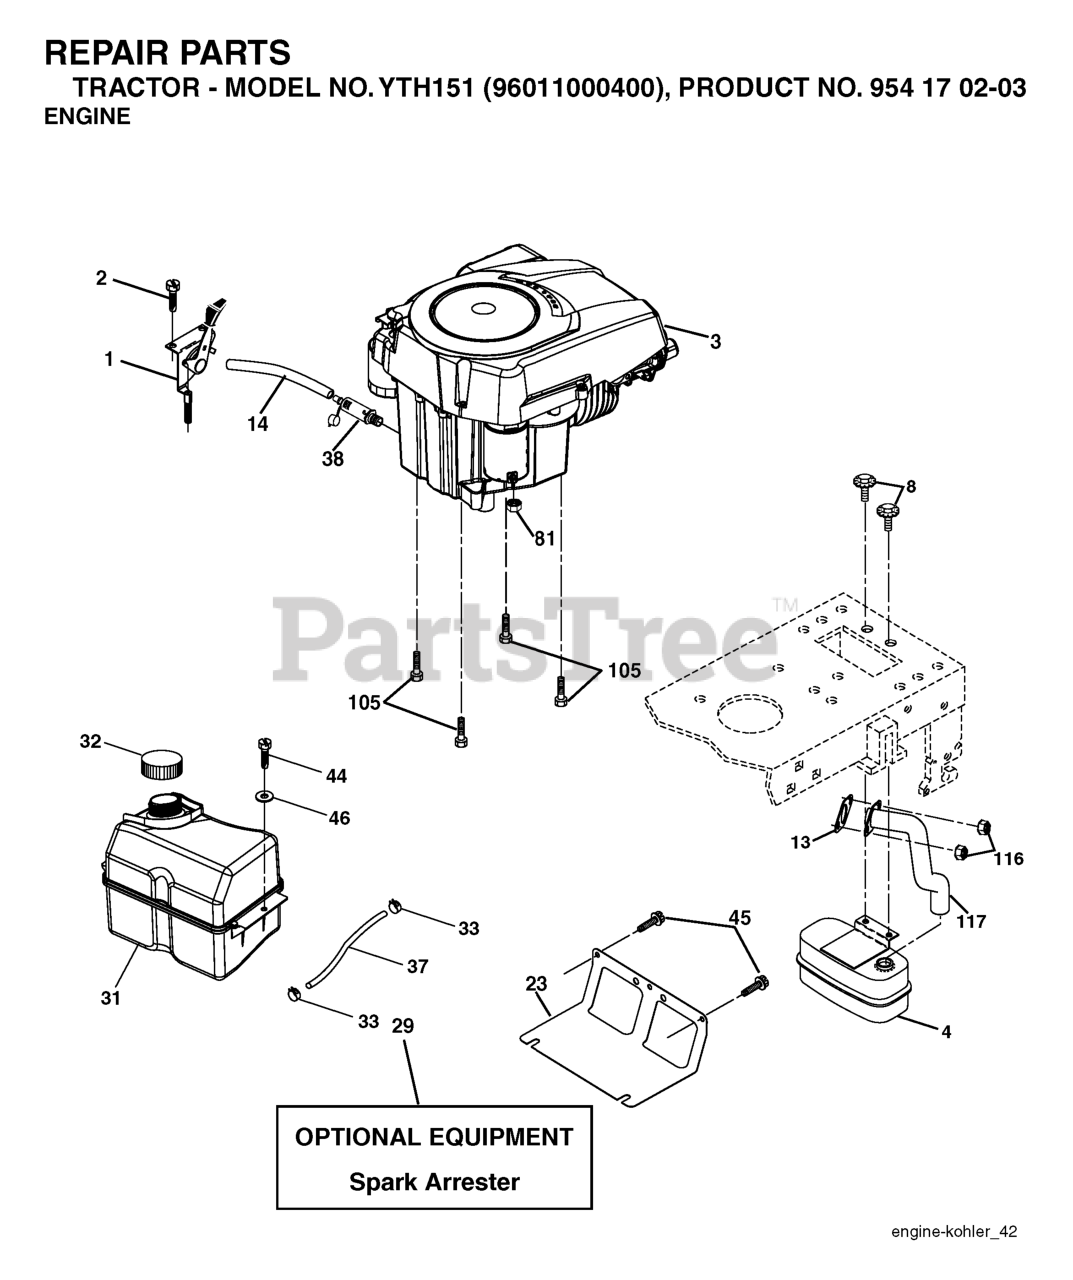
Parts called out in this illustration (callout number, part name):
1	CONTROL.THROTTLE.LT/YT
2	SCREW
4	MUFFLER.SINGLE.CYL.KOHL/B&S
8	BOLT.5/16-18UNCX3/4 W/SEMS.BLK
13	GASKET.EXHAUST.KOHLER
14	TUBE, DRAIN OIL ASM.
23	SHIELD.BROWNING.DBR.GUARD
29	KIT.SPARK ARRESTOR 794945 B&S
31	TANK FUEL
32	FUEL CAP
33	HOSE CLAMP
37	LINE.FUEL.20
38	PLUG DRAIN OIL EASY
44	SCREW HEXWSHR 1/4-20X3/4
45	SCREW, 3/8-16X3/4
81	NUT
105	SCREW 3/8-16X1
116	NUT.HEX.FLANGE.TOPLOCK
117	RP.TUBE.EXHAUST.KOHL.COURAGE
